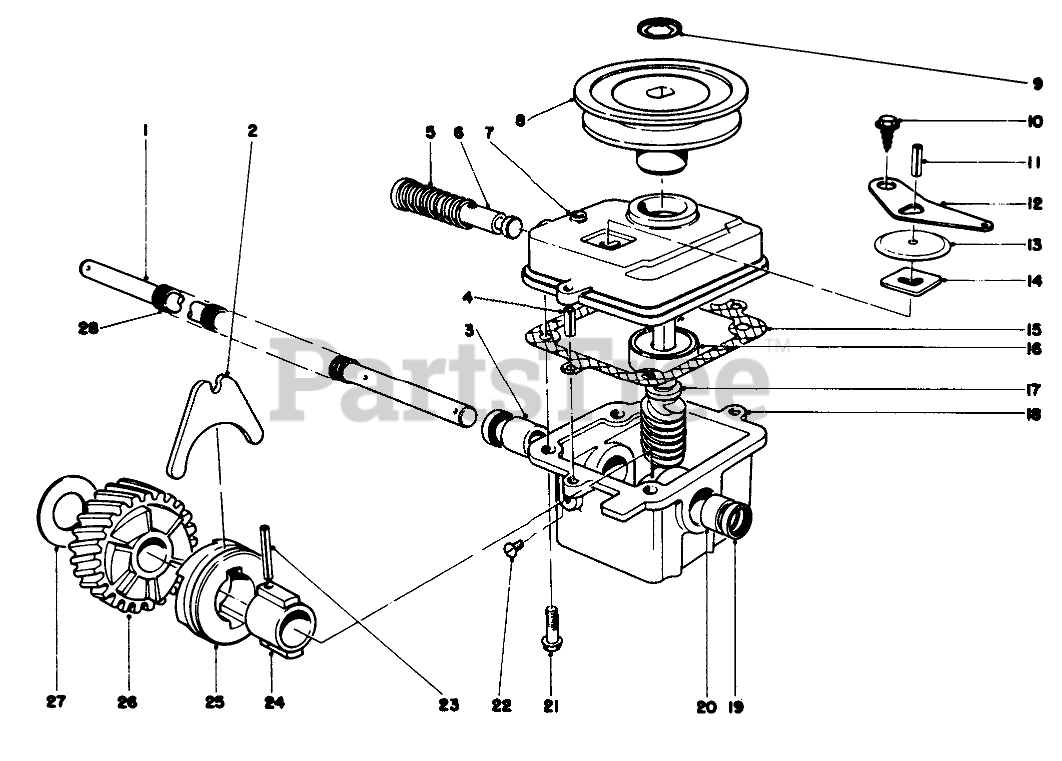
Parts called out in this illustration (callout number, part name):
1	DRIVE SHAFT (SERVCE)
2	SHIFTER FORK
3	Bushing
4	3/16 X 1/2 ROLL PIN
5	SPRING
6	Shift Rod
7	Case-Upper
8	PULLEY
9	PUSH-ON 93-3236
10	Screw
11	PIN-ROLL
12	SHIFTER ARM
13	TRANS DUST COVER
14	LATCH PLATE
15	GASKET
16	Bearing
17	Worm Shaft (Incl. Ref. #26)
18	Gear Case (Incl. Ref. #3, 19-20)
19	Seal
20	Bushing
21	Screw
22	NYLON SCREW
23	COIL PIN
24	SLEEVE
25	CLUTCH JAW
26	Helical Gear
27	THRUST WASHER
28	COVER-SHAFT, DRIVE
